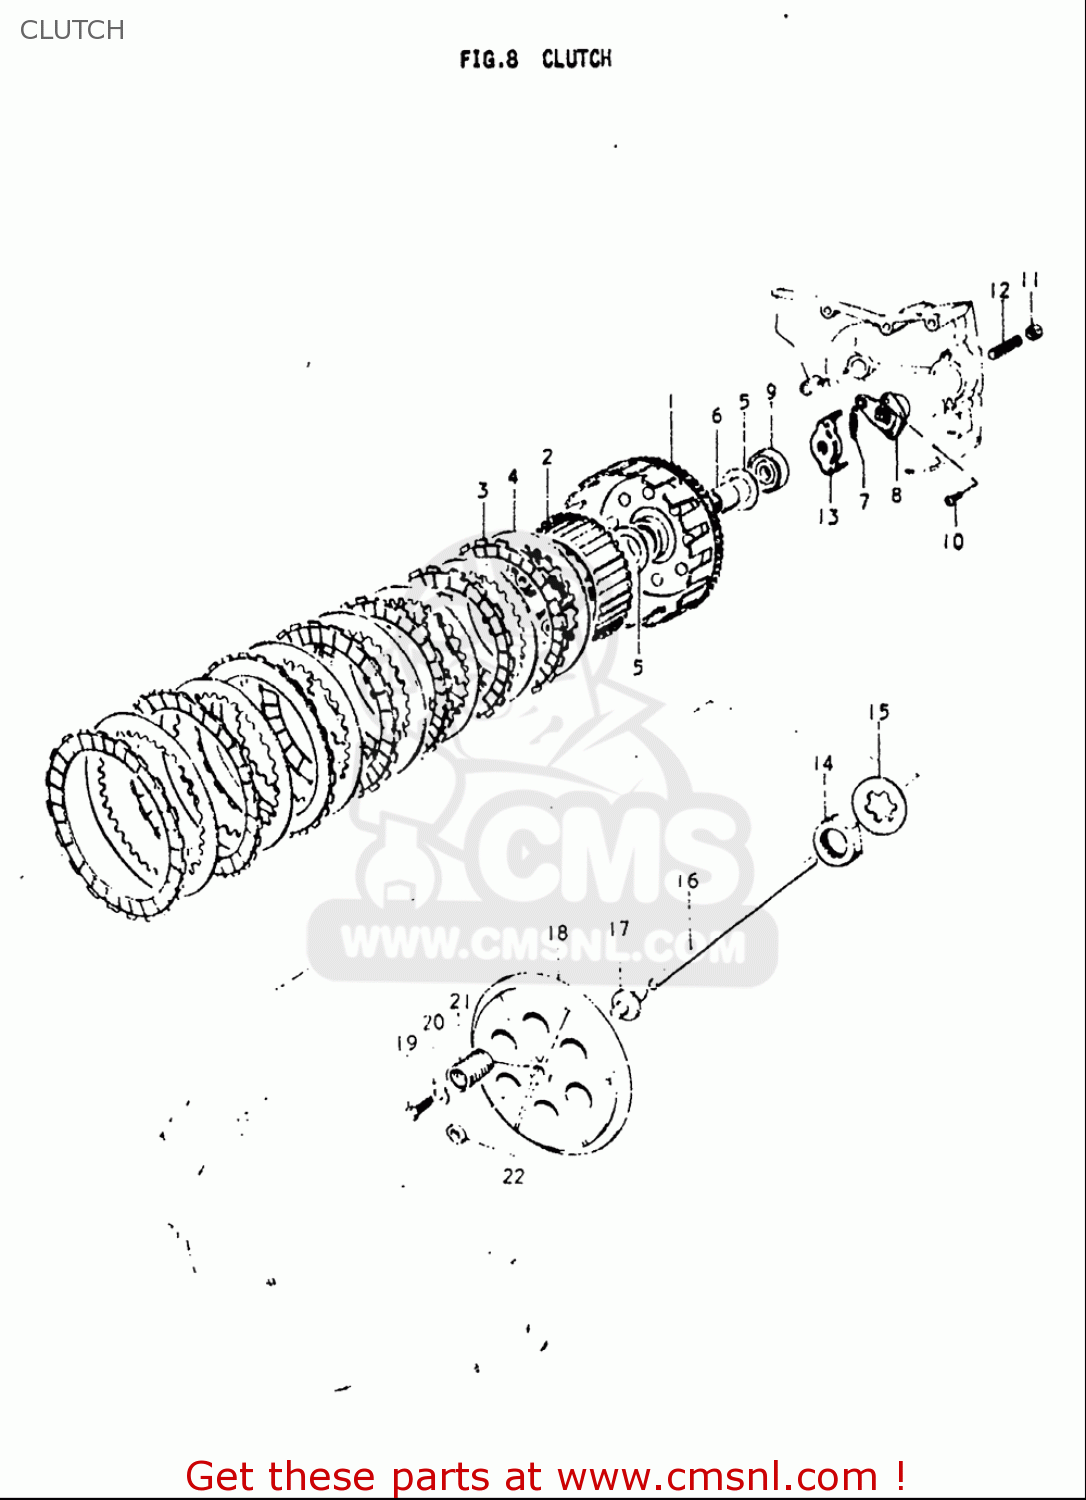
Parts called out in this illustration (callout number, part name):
4	PLATE,CLUTCH DRIVEN(T:2.0) (NAS)
5	WASHER
6	SPACER
7	SPRING
9	SEAL,OIL(8X32X6.5)
10	SCREW
11	NUT
12	SCREW
14	NUT
15	WASHER,LOCK
19	BOLT
20	WASHER(6.5X20X1.6)
21	SPRING
22	SEAL,OIL (10X17X5)
